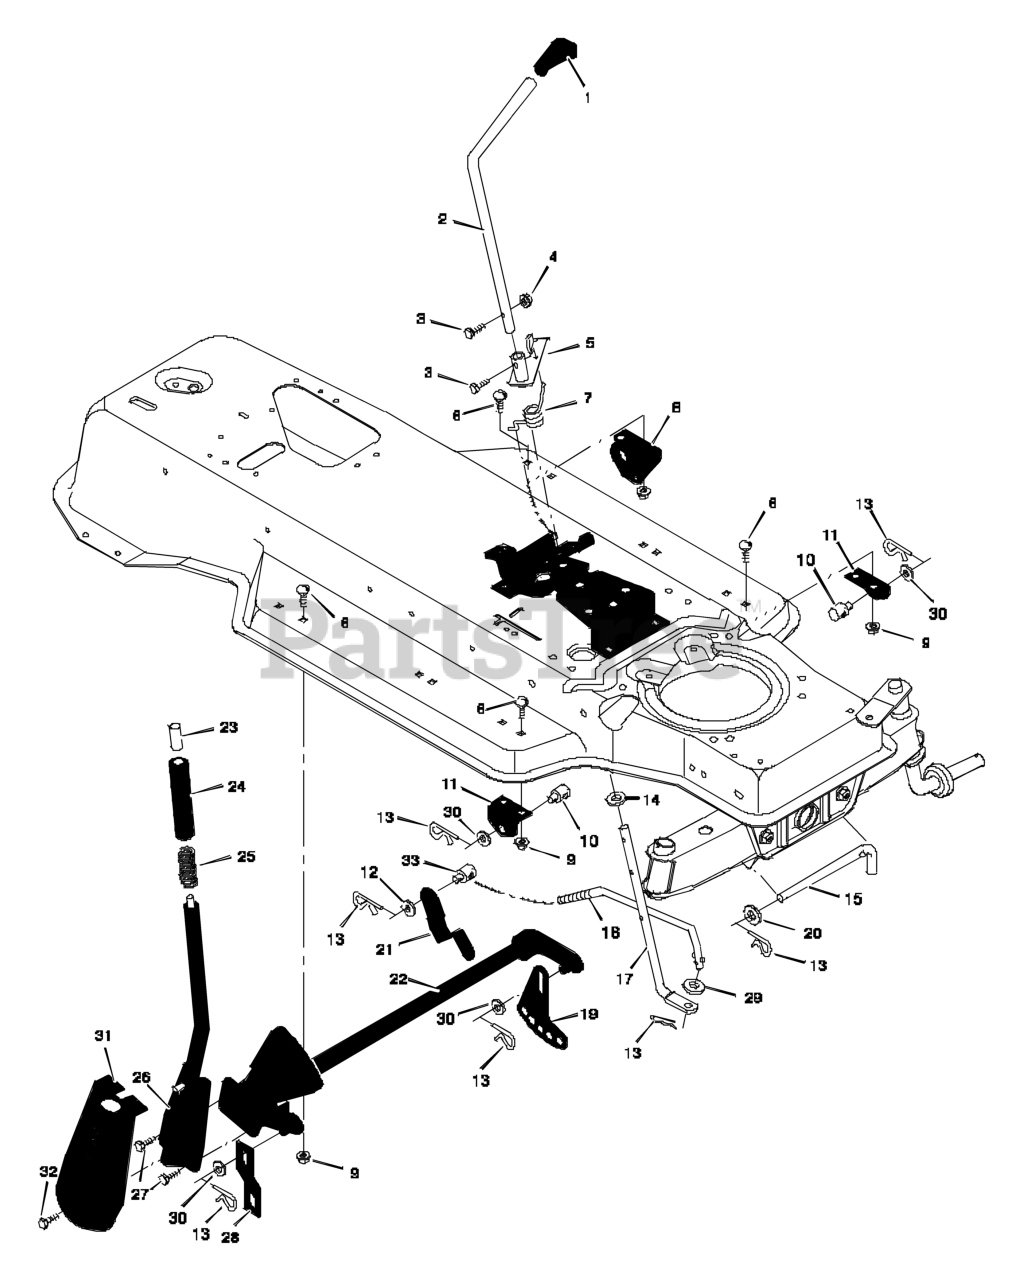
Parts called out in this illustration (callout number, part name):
1	Grip
2	Control, Blade Rotation
3	Screw, Hex
4	Locknut, Hex
5	Lever Assembly, Switch
6	Bolt, Carriage
7	Spring, Torsion
8	Bracket, Rear Hanger
9	Nut, Flange
10	Nut, Adjusting
11	Bracket, Adjuster Rod
13	Pin, Hair
14	Washer
15	Pin, Pull
17	Lever, Lower Blade Control
18	Rod, Blade Control
19	Plate, Adjuster
21	Bracket, Pivot
22	Lifter Assembly
23	Button, Push
25	Spring, Compression
26	Handle Assembly
28	Link, Suspension
29	Washer
31	Cover, Lift Lever
33	Nut, Adjusting
